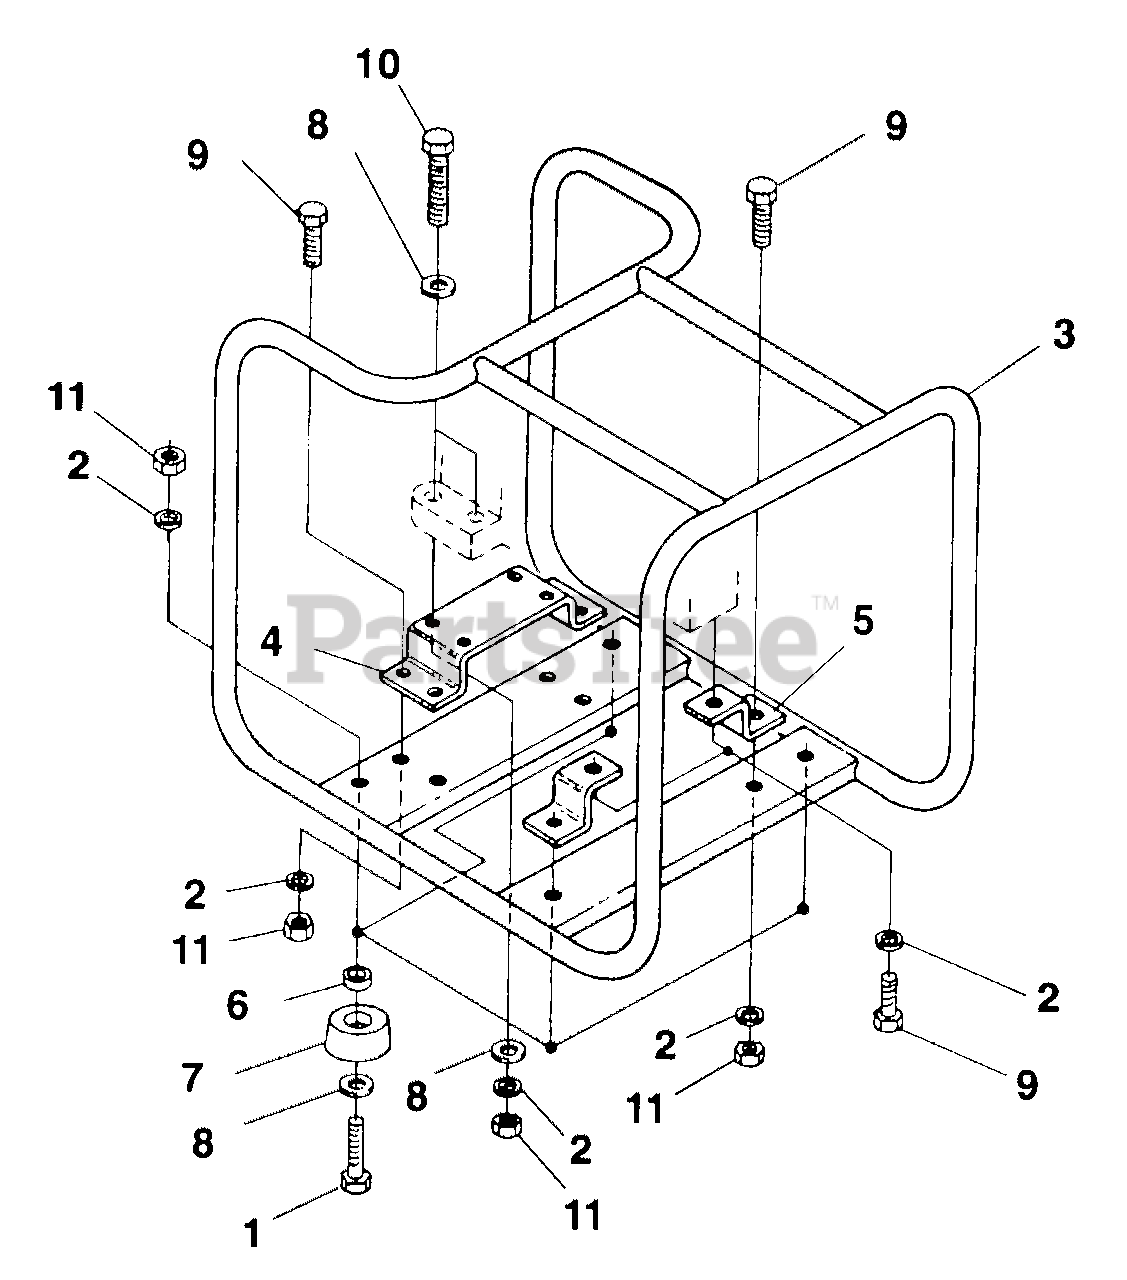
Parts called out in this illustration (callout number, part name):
1	HEX HD SCREW (5/16-18 X 1.25)
2	LOCK WASHER (5/16)
3	2" SERIES ROLL CAGE
4	ENGINE SUPPORT
5	PUMP SUPPORT
6	FOOT SPACER
7	RUBBER FOOT
8	FLAT WASHER (5/16)
9	HEX HD SCREW (5/16-18 X .75)
10	HEX HD SCREW (5/16-18 X 1.50)
11	HEX NUT (5/16-18)
